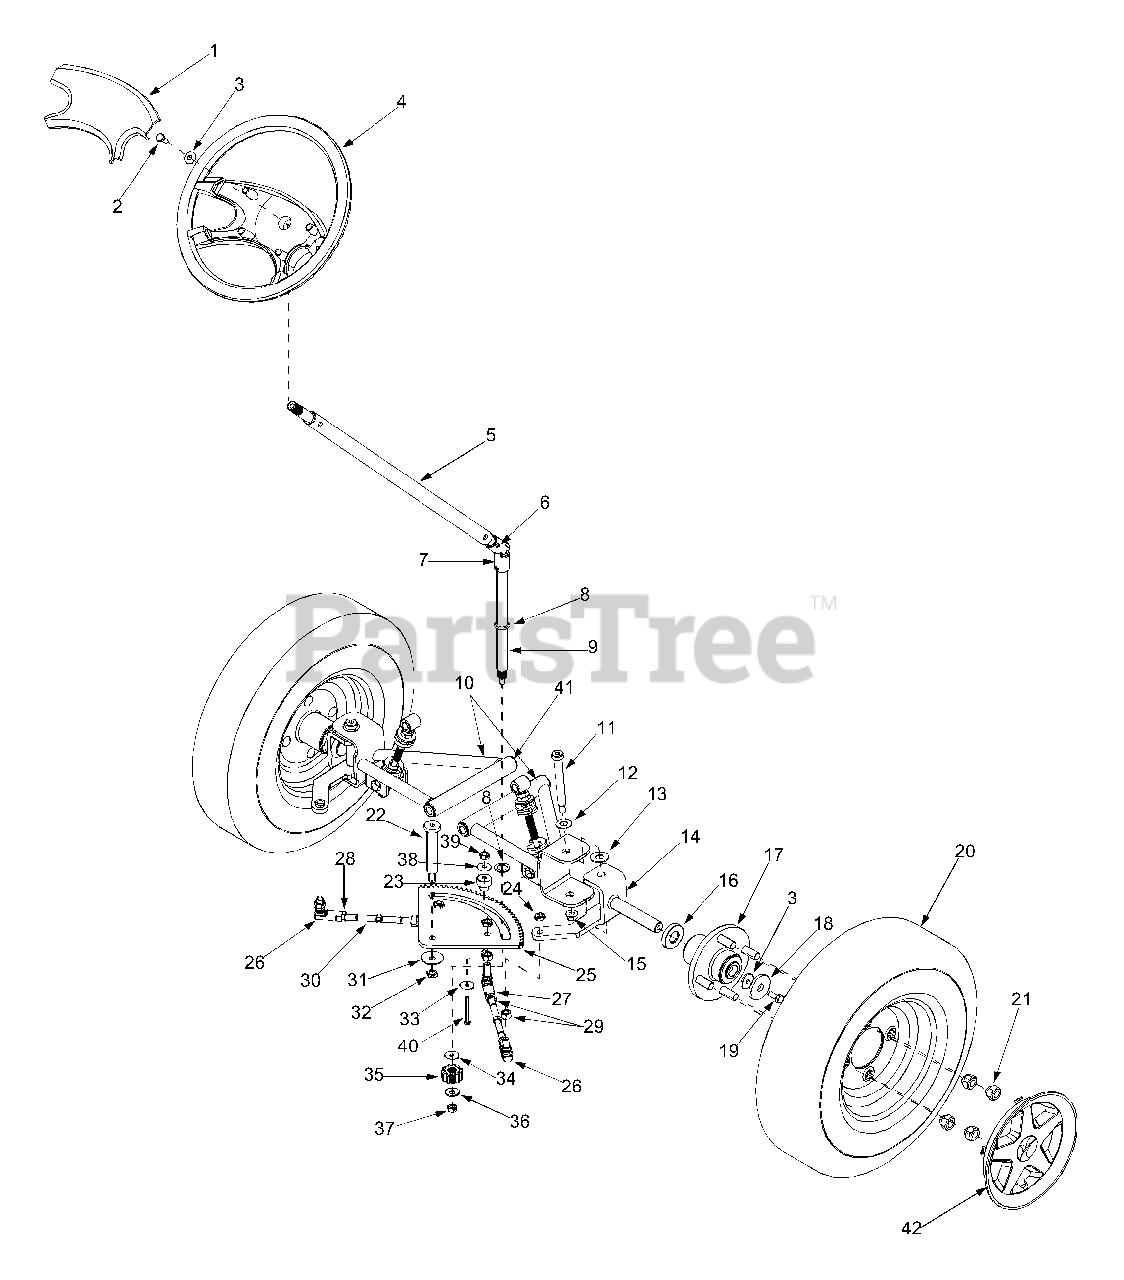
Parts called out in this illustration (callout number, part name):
1	Steering Wheel Cap
2	Hex Cap Screw 5/16-18 x 1.0
3	Bell Washer
4	Steering Wheel
5	Shaft Assembly
6	Spiral Pin
7	U-Joint Coupling
8	Flange Bearing .625 ID x .750 OD
9	Lower Steering Shaft
10	Front Arm Assembly - RH
11	Shoulder Screw .497 ID x 3.50 Lg
12	Bell Washer
13	Flat Washer .510 ID x 1.12 OD
14	Front Axle Assembly - LH
15	Flange Lock Nut 3/8-16
16	Axle Spacer .780 ID x 1.625 OD
17	Wheel Assembly Hub
18	Flat Washer .330 ID x 2.00 OD
19	Hex Cap Screw 5/16-24 x .750
20	Front Wheel Assembly
22	Shoulder Screw 3/8-24 x .625
23	Shoulder Spacer .26 ID x .875 OD
24	Hex Lock Nut 3/8-24
25	Gear Segment
26	Ball Joint 3/8-24
27	Ball Joint 3/8-24
28	Jam Nut 3/8-24
29	Hex Nut 3/8-24
30	Tie Rod 3/8-24 x 5.5
31	Bell Washer .39 ID x 1.38 OD
32	Hex Lock Nut 3/8-24
33	Flat Washer .281 ID x .875 OD
34	Flat Washer.625 ID x 1.0 OD
35	Steering Pinion Gear
36	Bell Washer .340 ID x .872 OD
37	Hex Lock Nut 5/16-24
38	Flat Washer .285 ID x .25 OD
39	Hex Lock Nut 1/4-20
40	Hex Cap Screw 1/4-20 x 2.75
41	Flange Bearing .501ID x .626 OD
42	Hubcap
